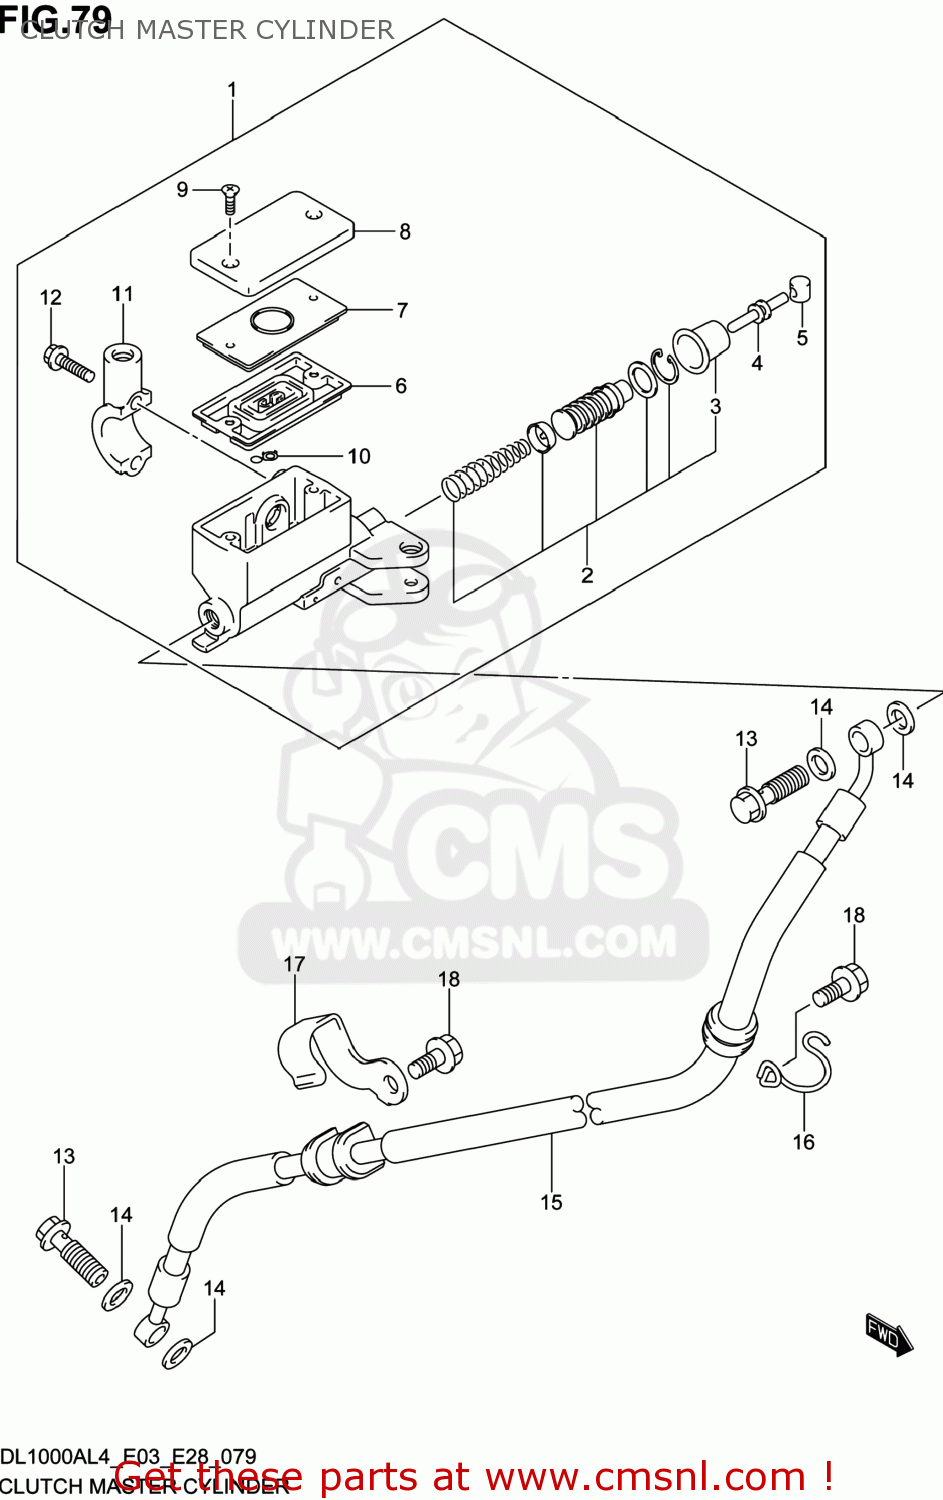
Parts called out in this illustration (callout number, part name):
1	CYLINDER ASSY,CLUTCH MASTER
2	PISTON & CUP SET
3	BOOT
4	ROD,PUSH
5	BUSH
6	7
7	PLATE,DIAPHRAGM
8	CAP
9	SCREW
10	PROTECTOR
11	HOLDER
12	BOLT(6X22)
13	BOLT UNION
14	WASHER(10X15X1.5)
15	HOSE,CLUTCH
16	CLAMP,CLUTCH HOSE NO.1
17	CLAMP,CLUTCH HOSE NO.2
18	BOLT
